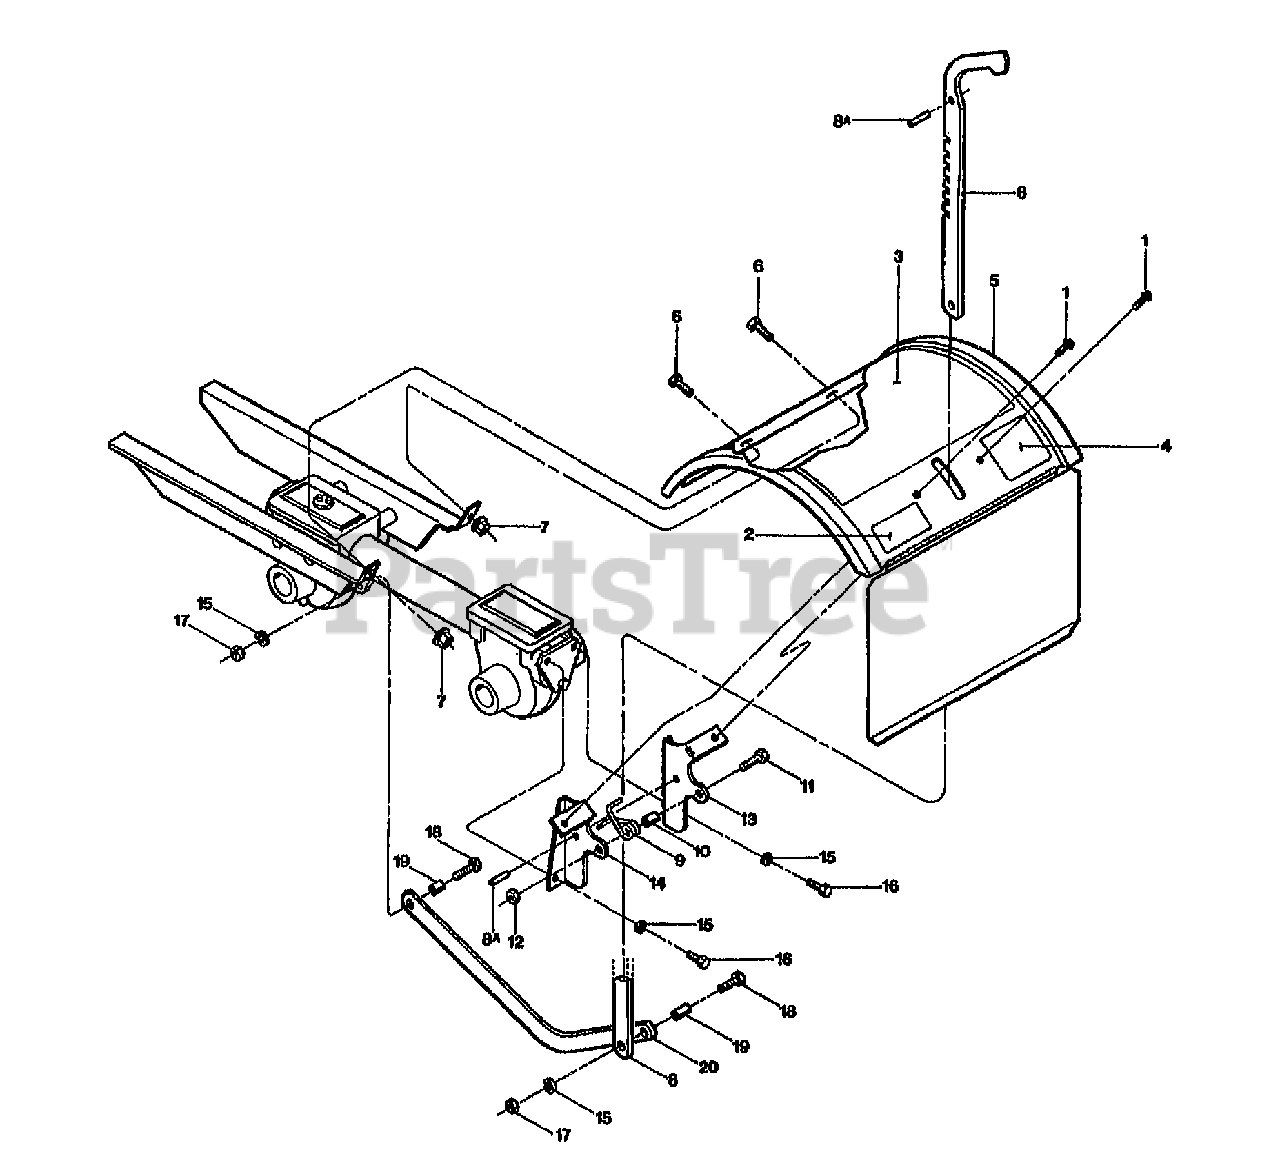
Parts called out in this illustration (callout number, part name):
1	SCR-HWH 1/4-20 X .5 STH
2	DECAL-LOGO TUFFY HOOD
3	DECAL-HOOD TUFFY (OPERATING & SAFETY INSTRUCTIONS)
4	DECAL-TINE WARN SM FRAME
5	HOOD W/DECALS PNT (INCL. TINE FLAP, 55054, 55051, & 20814)
6	SCR-HH 5/16-18X.5 GD5 YEL
7	NUT-HFLK 5/16-18 ZP
8	DEPTH REG-W/PIN PNT
8A	PIN-ROLL .25 X 1
9	SPRING-TORSION
10	SPACER-.250X.343X.375
11	SCR-HH 1/4-20X1.0
12	NUT-LK 1/4-20
13	BRKT-HOOD RIGHT PNT
14	BRKT-HOOD LEFT PNT
15	WASHER-LK .312 ZP
16	SCR-HH 5/16-18X1.0 G5 ZP
17	NUT-HEX 5/16-18 ZP
18	SCR-HH 5/16-18X1.25 G5ZP
19	BUSHING-.438X.323X.4
20	DRAG BAR-TUFFY PNT
